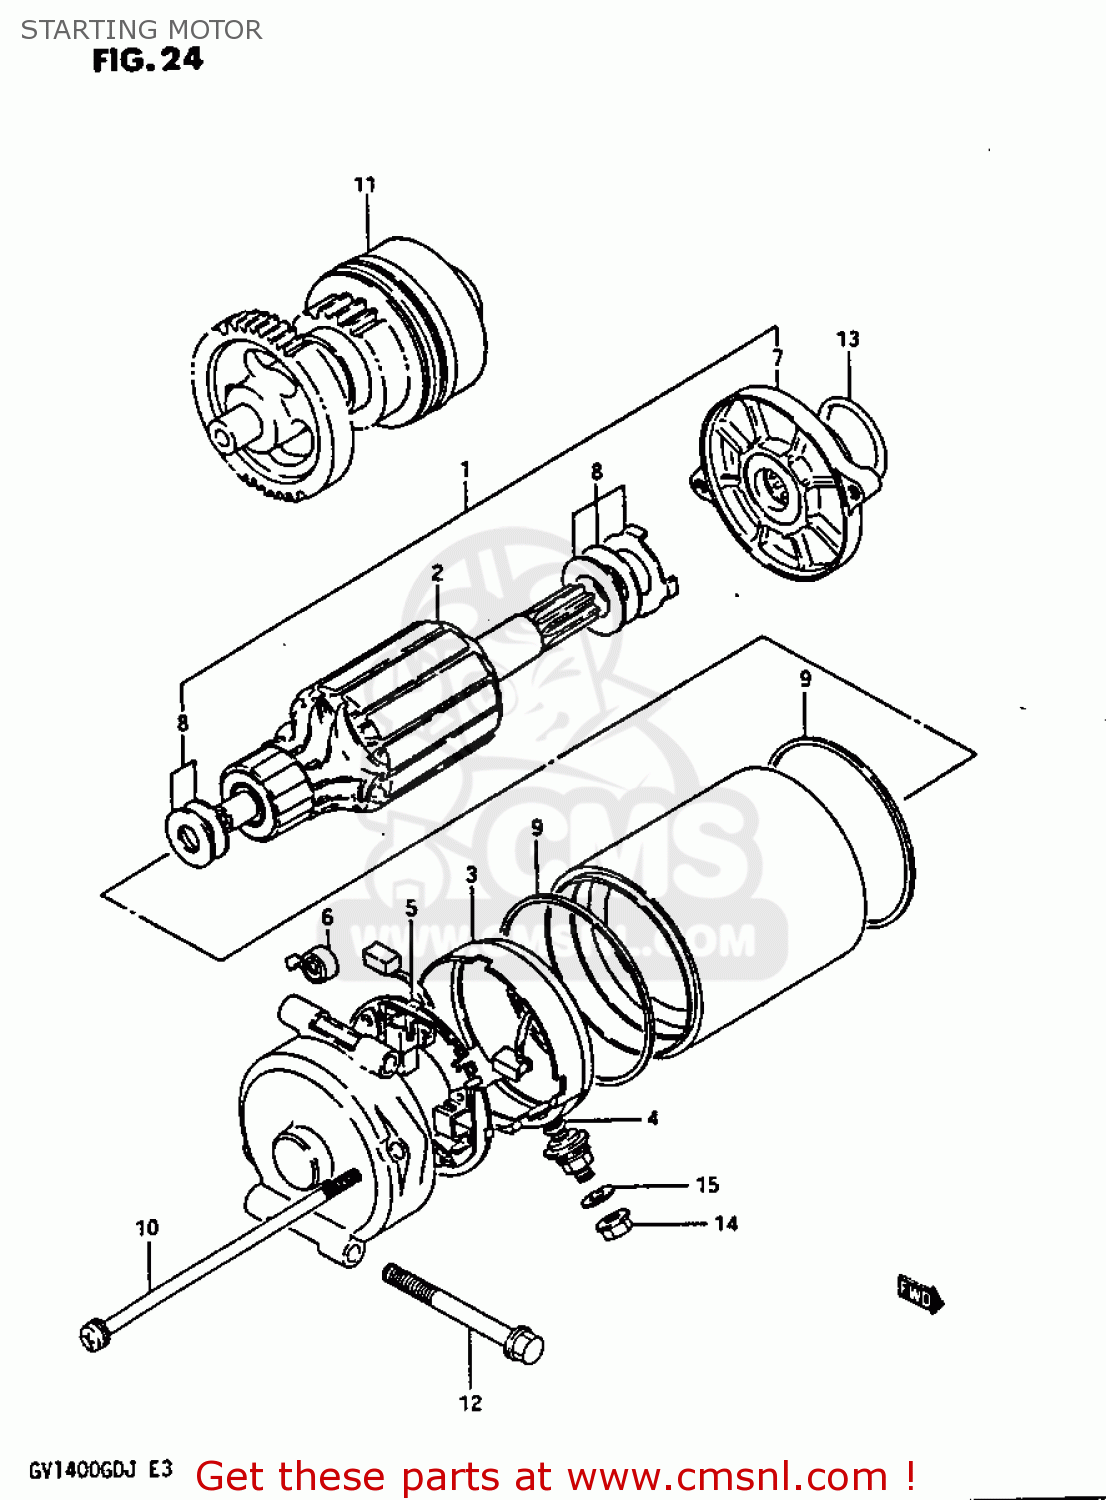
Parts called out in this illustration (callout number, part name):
1	MOTOR ASSEMBLY,STARTING
2	ARMATURE
3	BRUSH TERMINAL SET
4	O RING
5	HOLDER,BRUSH
6	SPRING,BRUSH
7	BRACKET SET,STARTING MOTOR
8	SHIM SET,STARTING MOTOR
9	SEAL,RING
10	BOLT
11	PINION ASSEMBLY,STARTING MOTOR
12	BOLT (6X60)
13	O RING(D:3,ID:24.5)
14	NUT
15	WASHER,LOCK
